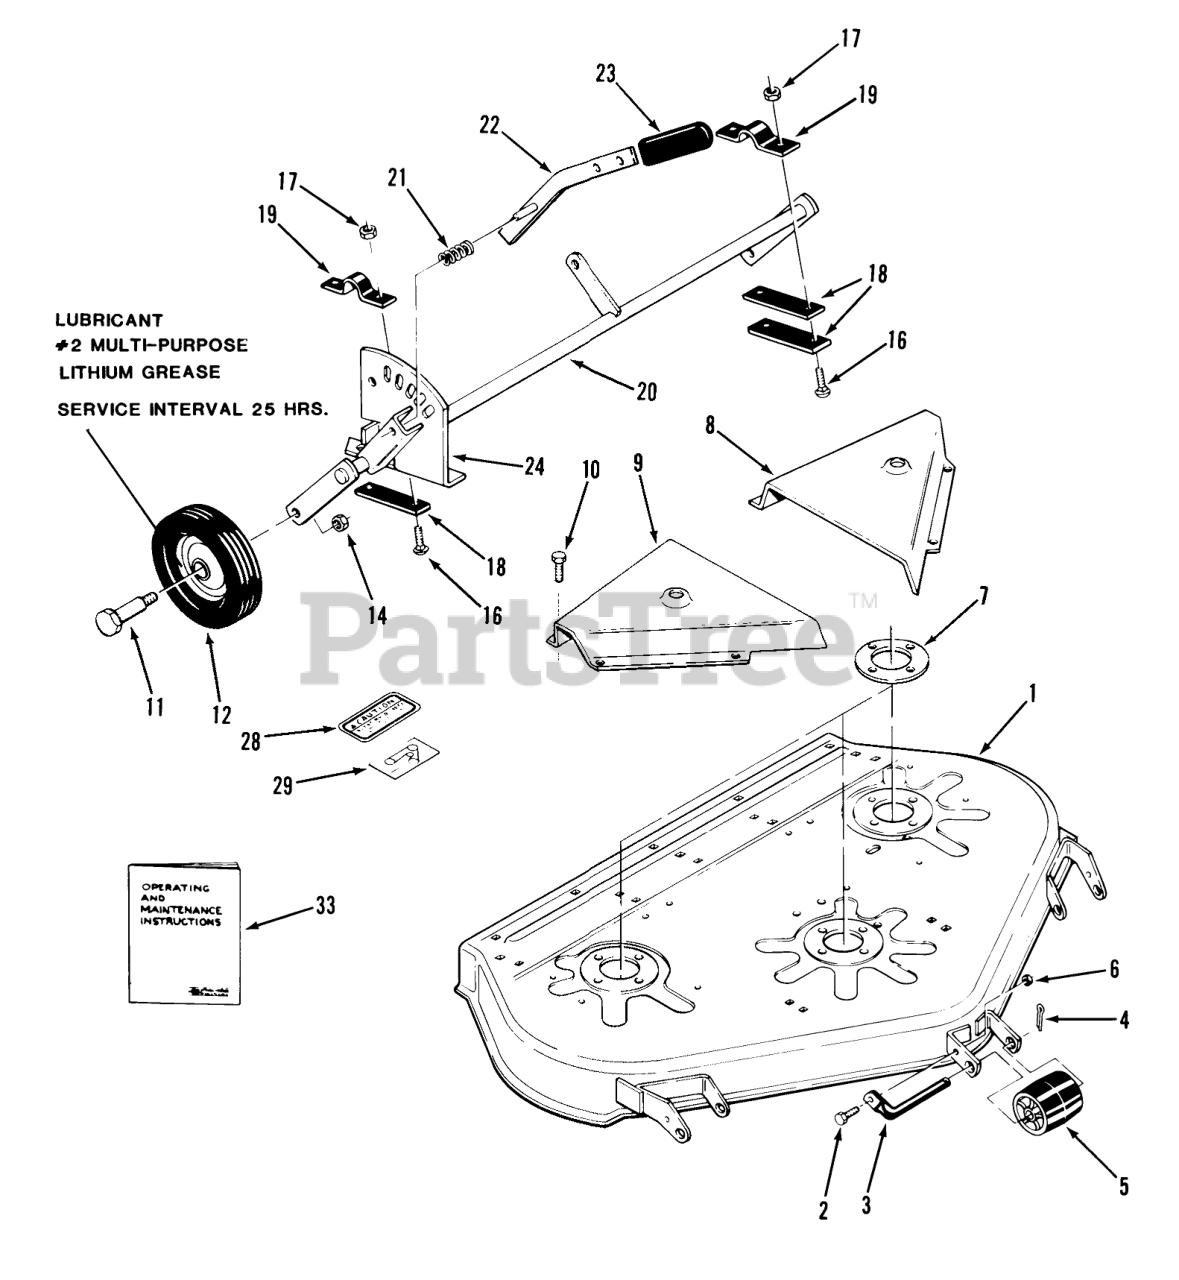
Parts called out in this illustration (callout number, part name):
1	Mower Deck
2	H H C S
3	ROLLER-SHAFT
4	Cotter Pin
5	Roller
6	Nut
7	PLATE-SPINDLE
8	Belt Cover LH
9	Belt Cover RH
10	Bolt
11	BOLT-SHOULDER
12	WHEEL
14	Nut
16	Bolt
17	Nut
18	Bar
20	ASSY GAUGE WHEEL R
21	SPRING-COMPRESSION
22	Lever
24	Quadrant
28	Caution Decal
29	DECAL-HEIGHT & BELT
33	Operating and Maintenance Instructions
